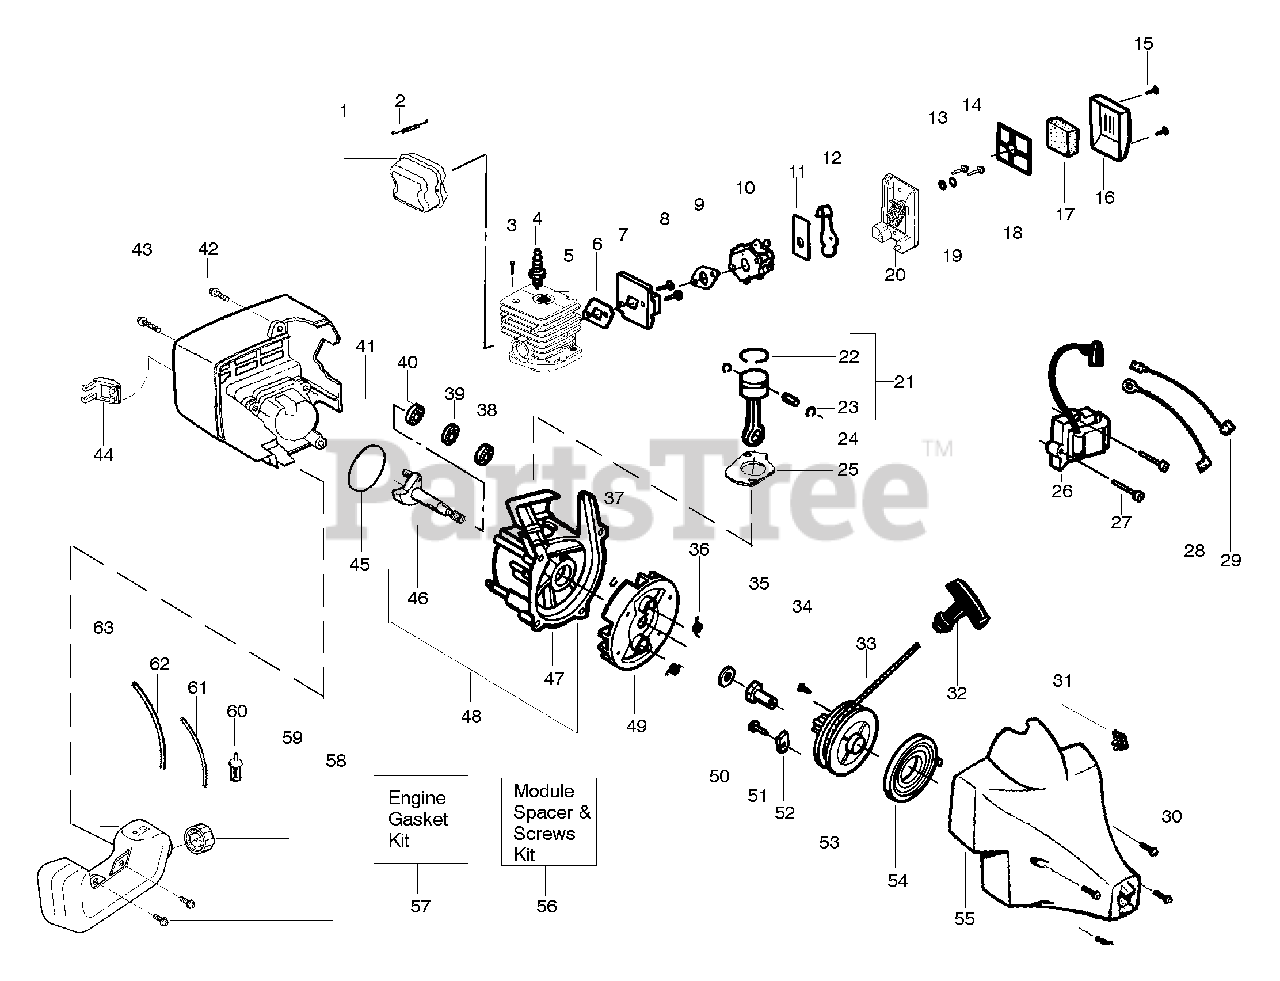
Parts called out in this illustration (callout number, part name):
1	Kit - Muffler
2	Muffler Spring
3	Screw-Cylinder
4	Spark Plug (RCJ 6Y)
5	Kit - Cylinder
6	Gasket-Cyl/Carb.(kit)
7	Adaptor-carb.
9	Gasket-Carb.(kit)
10	Kit - Carburetor Ass'y (WT-631)
11	Plate-Choke Mounting
12	Lever-Choke
16	Cover-Air Box
17	Foam-Air Filter
18	Plate-Air Filter Support
19	Spacer-Choke
21	Kit - Piston
22	Piston Ring
23	Retainer-Piston Pin
24	Assy-Connecting Rod
25	Gasket-Cylinder(kit)
26	Ignition Module
28	Assy-Ground Wire
29	Assy-Leadwire
30	Screw
31	Kit-Switch
32	Handle-Starter
33	Kit - Rope
35	Coupling-Drive
36	Spring-Starter Dog
37	Retain. Ring-C'shaft
38	Bearing-Outer
39	Seal-C'case
40	Bearing-Inner
43	Screw
44	Guard-Muffler
45	O-Ring-C'case(kit)
46	Assy-Crankshaft
47	Assy-Crankcase
48	Assy-C'case & C'shaft
49	Assy-Flywheel
50	Washer-Flat
52	Retainer-Can
53	Kit-Starter Pulley
54	Spring-Starter
55	Assy-Fan Housing
56	Kit-Module Spacer & Screws
57	Kit-Engine Gasket
58	Retainer-Tank
59	Assy-Fuel Cap
60	Assy-Fuel Pickup
61	Kit-Fuel Line
62	Kit-Fuel Line
63	Assy-Fuel Tank
